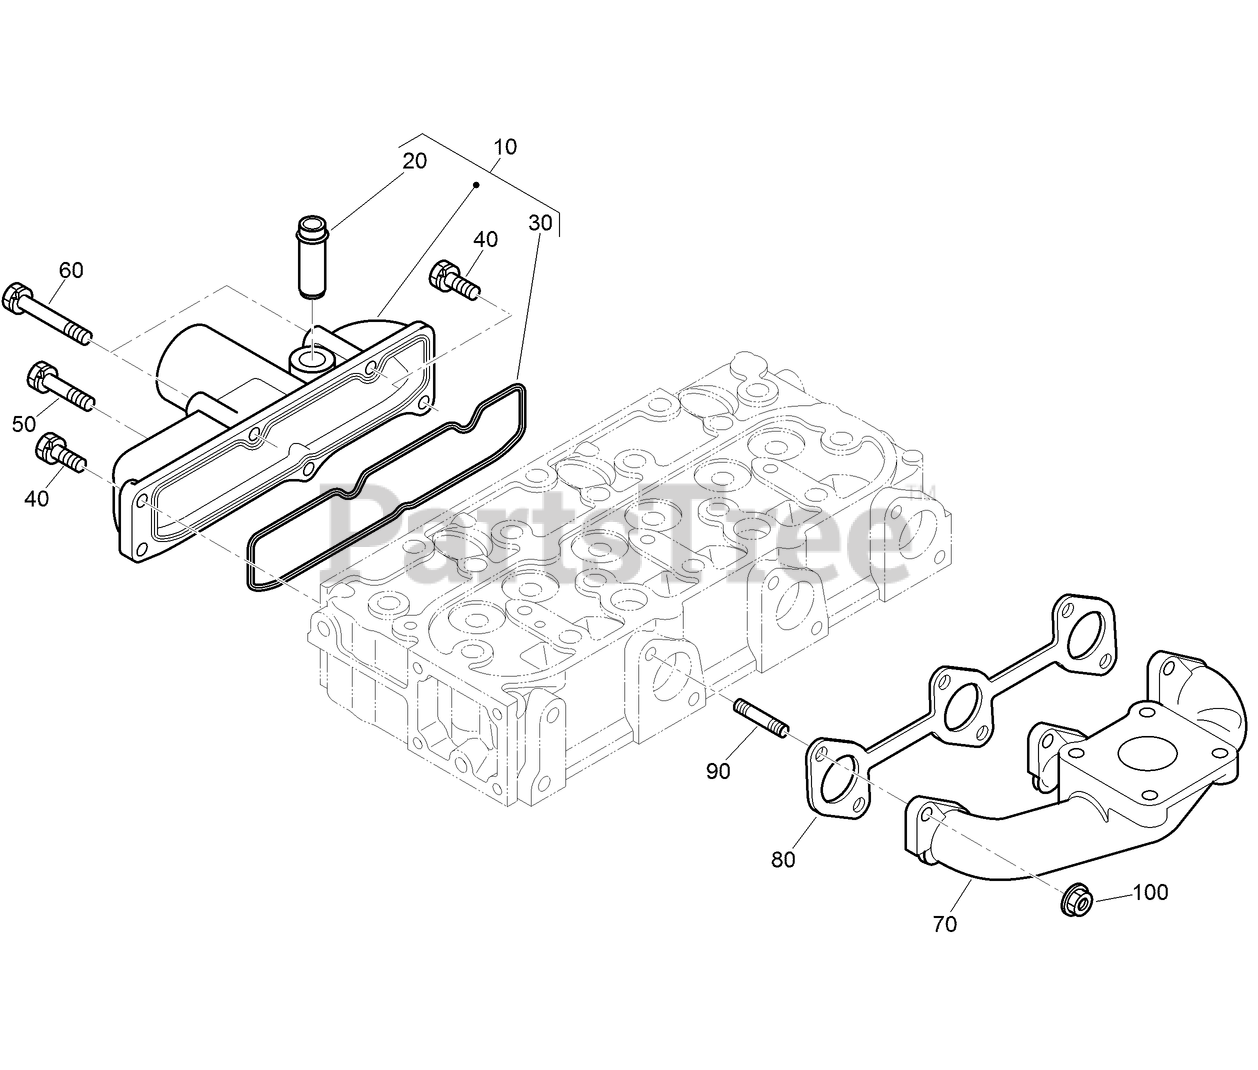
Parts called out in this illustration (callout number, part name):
10	INLET MANIFOLD ASM
20	JOINT-PIPE, BREATHER
30	GASKET-MANIFOLD, INLET
40	BOLT-FLANGE
70	MANIFOLD-EXHAUST
80	GASKET-MANIFOLD, EXHAUST
